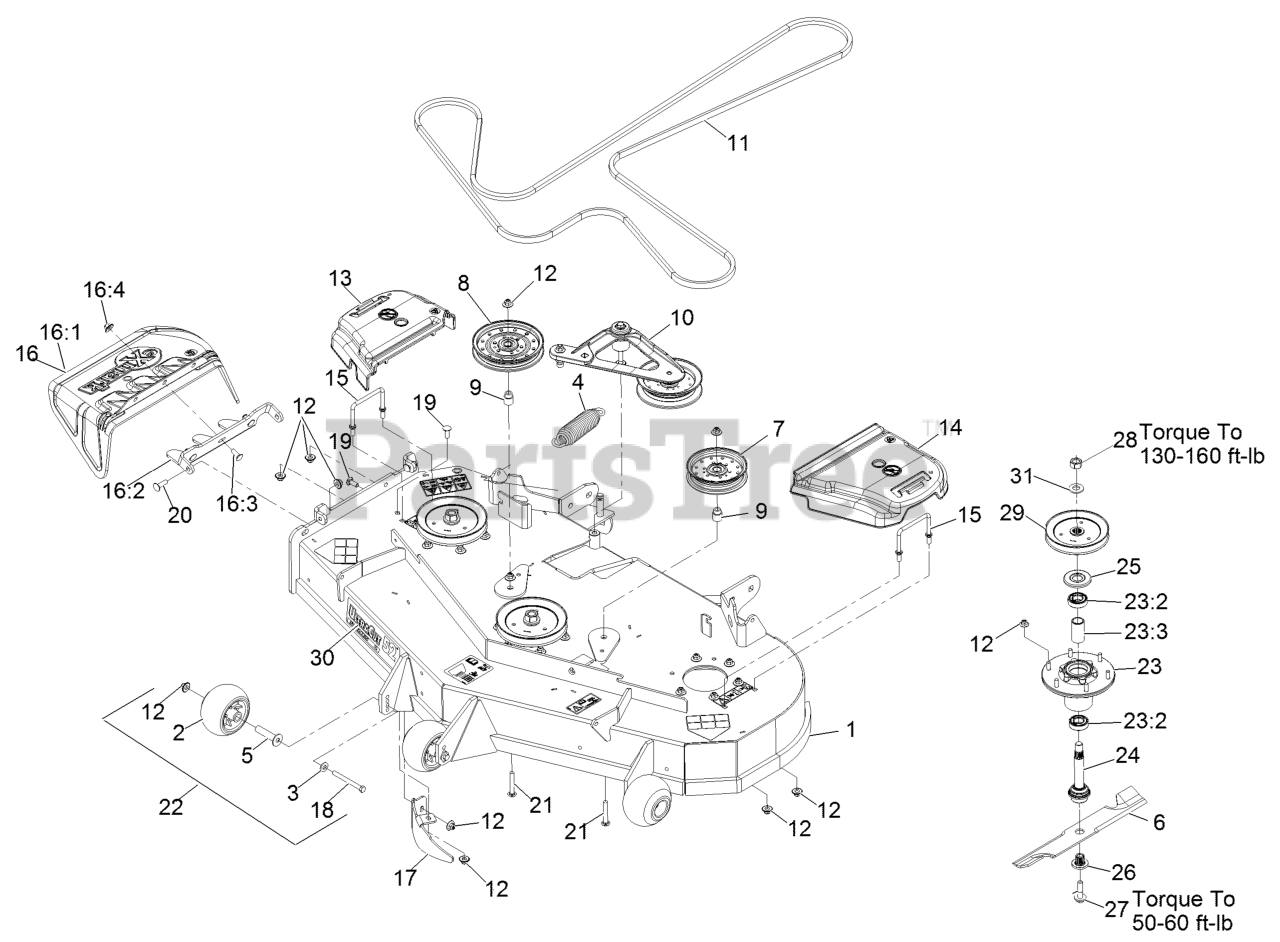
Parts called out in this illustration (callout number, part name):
1	ASM,DECK W/ DECALS 52
2	ROLLER-SCALP, ANTI
3	WASHER-BELLEVILLE
4	SPRING-EXTENSION
5	AXLE, ROLLER
9	BUSHING-IDLER
10	DECK IDLER ASM
11	BELT,V-B X 186.00"
12	Nut-Nyloc 3/8-16 Flg
13	COVER-BELT, RH
14	COVER-BELT, LH
15	WIREFORM-COVER
16	ASM,DISCHARGE CHUTE
16:1	CHUTE,DISCHARGE
16:2	BRACKET,DISCHARGE CHUTE
16:3	SCREW-CARR
16:4	Nut-Nyloc 3/8-16 Flg
17	BAFFLE-DOGLEG, LZ-VT52
18	SCREW-HH 3/8-16 X 3 3/4 GR 8
19	SCREW-CARR
20	Bolt-Carriage 3/8-16 X 1 1/4
21	SCREW-CARR
22	KIT, ANTI-SCALP ROLLER
23	ASM-CUTTER HSG WITH BEARINGS
23:2	BEARING-BALL
23:3	SPACER-BEARING
24	ASM-SPINDLE AND SEAL
25	GUARD,BEARING TOP .989
26	BUSHING,SPLINED
27	SCREW,SEMS 1/2-20 X 2.19
28	NUT-HEX
29	SHEAVE,BLADE DRIVE 6.50
30	DECAL,ULTRACUT 52 SERIES
